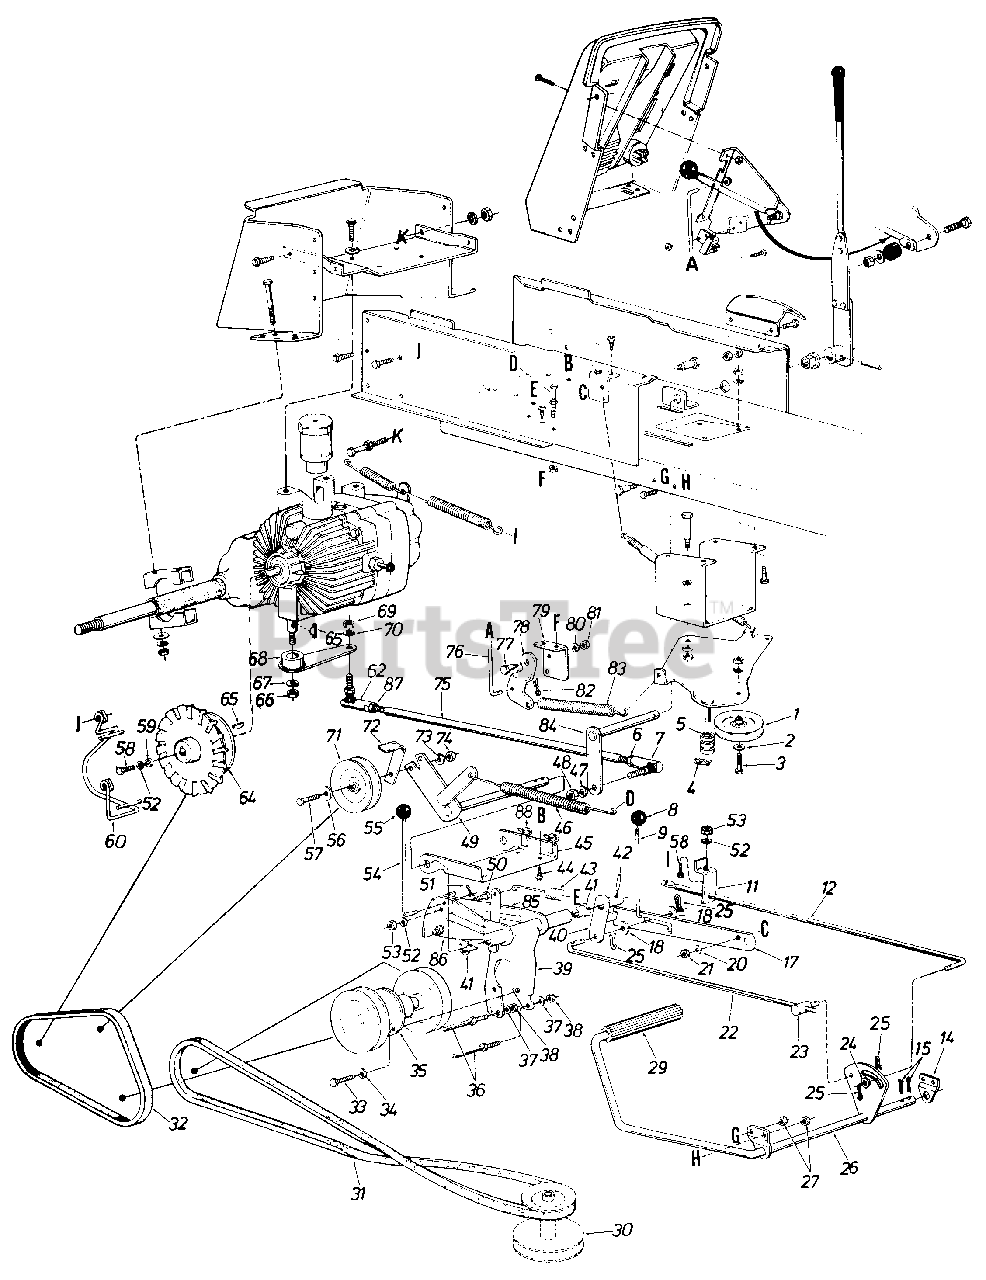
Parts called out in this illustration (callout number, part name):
1	4" Dia. "V"-Idler Pulley
2	Fl-Wash. 3/8" I.D.
3	Hex Bolt 3/8-16 x 1.25" Lg.*
4	Intern. Cotter Pin 5/16" Dia.
5	Spacer
6	Hex Jam L-Nut 3/8-24 Thd.
7	Ball Joint Ass'y. 3/8-24 Thd.
8	Ball Knob
9	Parking Brake Link
11	Brake Rod Hanger
12	Brake Rod
14	Clutch Rod Brg. Brkt.
15	Cotter Pin 1/8" Dia. x 1.00" Lg. *
17	Parking Brake Cam
18	Fl-Wash. .406" I.D. x 1.00" O.D. x .030"
20	L-Wash. 5/16" I.D.*
21	Hex Nut 5/16-18 Thd.*
22	Brake Cam Rod
23	Pivot Bushing
24	Fl-Wash. .401" I.D. x .749" O.D. x .057" Thk.
25	Cotter Pin 3/32" Dia. x .75"
26	Clutch Brake Pedal Ass'y.
27	Hex L-Nut 3/8-16 Thd.
29	Foot Pad
30	Two-Step Engine Pulley 4.75" and 5.56"
31	I'V"-Belt
32	"V"-Belt
33	Hex Sems Bolt 5/16-18 x .75" Lg.*
34	L-Wash. 5/16" I.D.*
35	Jack Shaft Ass'y.
36	Stud 3/8-16 x 3.62" Lg.
37	L-Wash. 3/8" I.D.*
38	Hex Nut 3/8-16 Thd.*
39	Jack Shaft Mtg. Brkt. Ass'y.
40	Clutch Idler Horn Ass'y.
41	Nyliner 5/8" I.D. x .88" Lg.
42	Spring Pin Spiral 1/4" Dia. x 1.5" Lg.
43	Ext. Spring
44	Hex Wash. Hd. Self-Tap Scr. 1/4-20 x .50" Lg.
45	Idler Mtg. Brkt.
46	Ext. Spring
47	L-Wash. 3/8" I.D.
48	Hex Nut 3/8-24 Thd.
49	Clutch Brkt. Ass'y.
50	Hex Bolt 1/4-20 x .50" Lg.
51	Internal Cotter Pin 5116" Dia. Rod
52	L-Wash. 1/4" I.D.
53	Hex Nut 1/4-20 Thd.
54	Relief Valve Lockout Rod
55	Ball Knob
56	Fl-Wash. 3/8" I.D.
57	Hex Bolt 3/8-16 x 1.25" Lg.
58	Hex Bolt 1/4-20 x .62" Lg.
59	Fl-Washer
60	Belt Guard Ass'y.
62	Ball Joint Ass'y. 3/8-24 L.H. Thd.
64	Transaxle Pulley w/Fan
65	Hi-Pro Key 118" x '/2" Dia.
66	Hex Nut 3/8-16 Thd.
67	L-Wash. 3/8" I.D.*
68	Pintle Arm Ass'y.
69	Hex Nut 3/8-24 Thd.
70	L-Wash. 3/8" I.D.
71	4" "V"-Idler Pulley
74	Hex Nut 3/8-16 Thd.
75	Speed Control Rod
76	Deck Control Rod
77	Shld. Scr. .437" Dia. x .162" Lg. (5/16-18)
78	Deck Control Pivot Brkt.
79	Parking Brake Cam Mtg. Brkt.
80	L-Wash. 5116" I.D.
81	Hex Nut 5/16-18 Thd.
82	Internal Cotter Pin 5116" Rod
83	Extension Spring
84	Speed Control Shaft Ass'y.
85	Relief Valve Cam-L.H.
86	Relief Valve Cam-R.H.
87	Hex Jam L-Nut 3/8-24 L.H. Thd.
88	Plastic Hose Clamp
